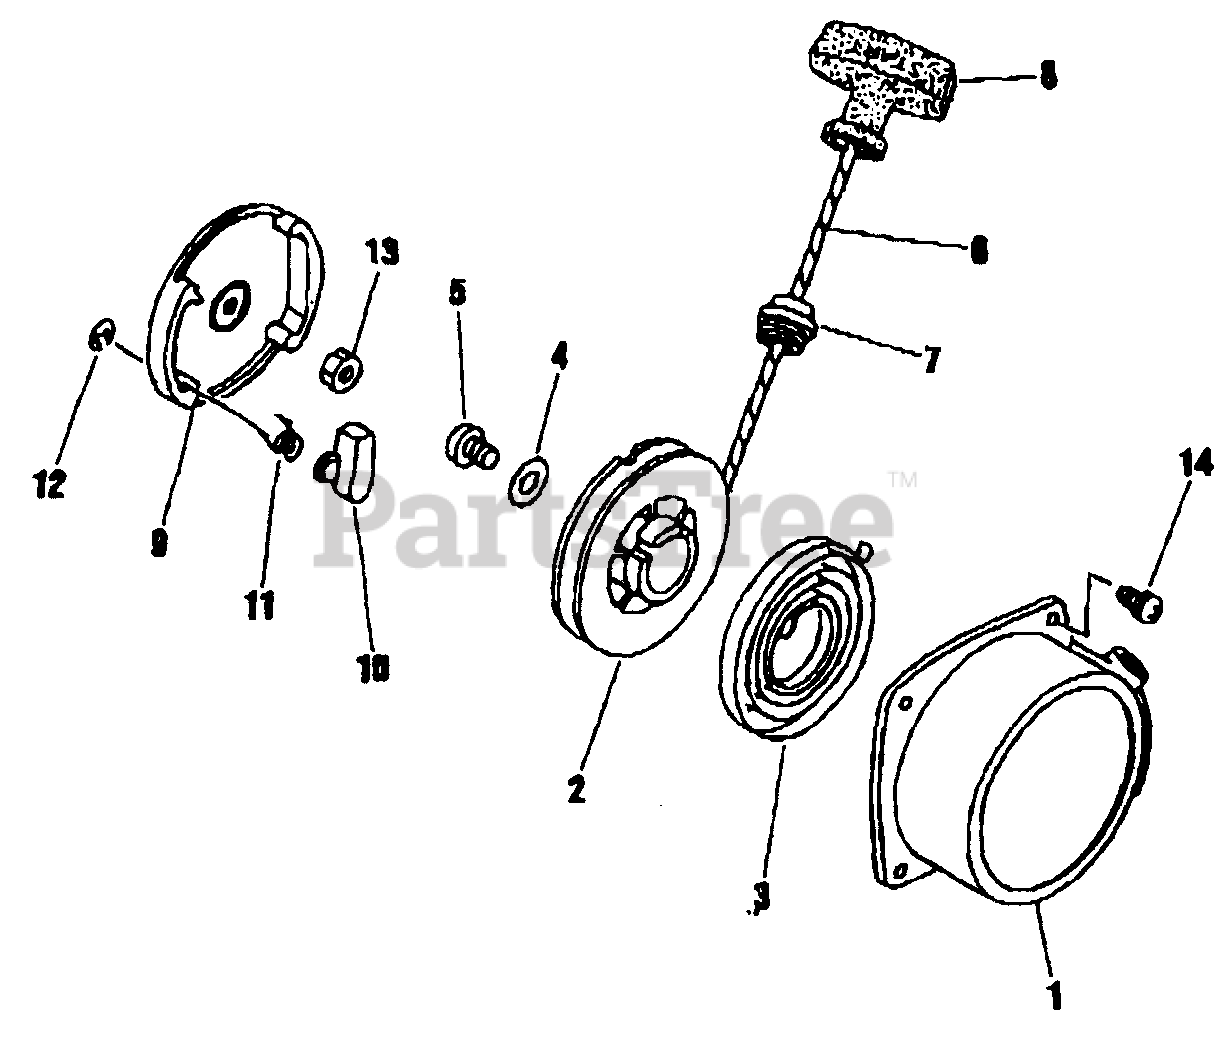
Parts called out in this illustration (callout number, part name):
1	CASE, STARTER
2	REEL, ROPE
3	SPRING, REWIND
4	WASHER
5	SCREW
6	ROPE, STARTER
7	GUIDE, ROPE
8	GRIP, STARTER
9	PULLEY
10	RATCHET
11	SPRING, RETURN
12	RING, RETAINING
13	NUT
14	SCREW - 4X12
